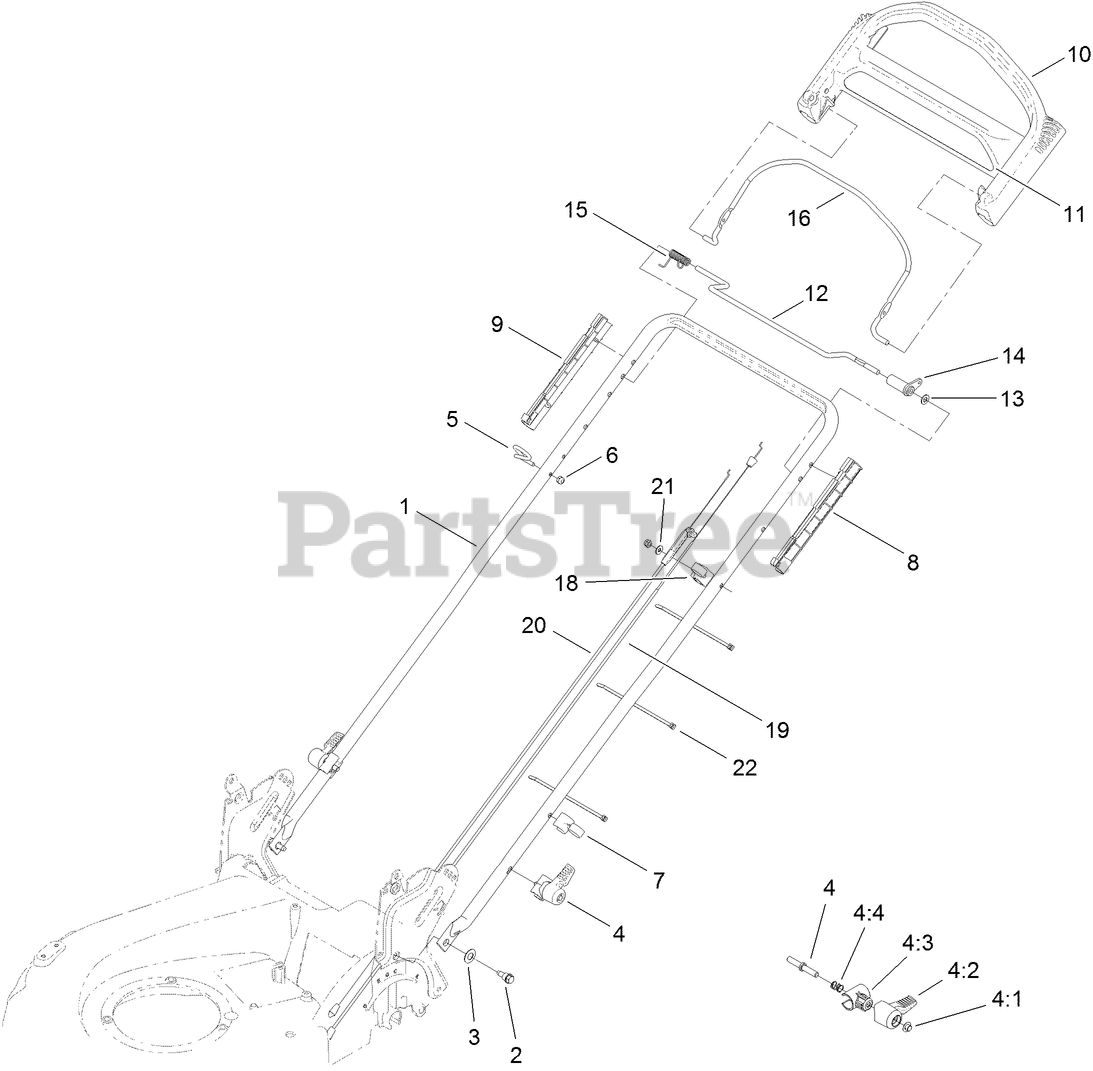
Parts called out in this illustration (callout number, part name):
2	BOLT-SHOULDER
3	WASHER-SPRING, CONICAL
4	QUICK RELEASE ASM
4:2	LEVER
4:3	ANCHOR-SPRING
4:4	SPRING-COMPRESSION
5	GUIDE-ROPE
6	NUT-LOCK, NI
7	GUIDE-CABLE
8	GUIDE-LH
9	GUIDE-RH
10	HANDLE-CONTROL
11	DECAL-HANDLE
13	WASHER-PLAIN
14	LEVER-TRACTION
19	CABLE-TRACTION
20	CABLE-BRAKE
21	WASHER-FLAT
22	TIE-CABLE
